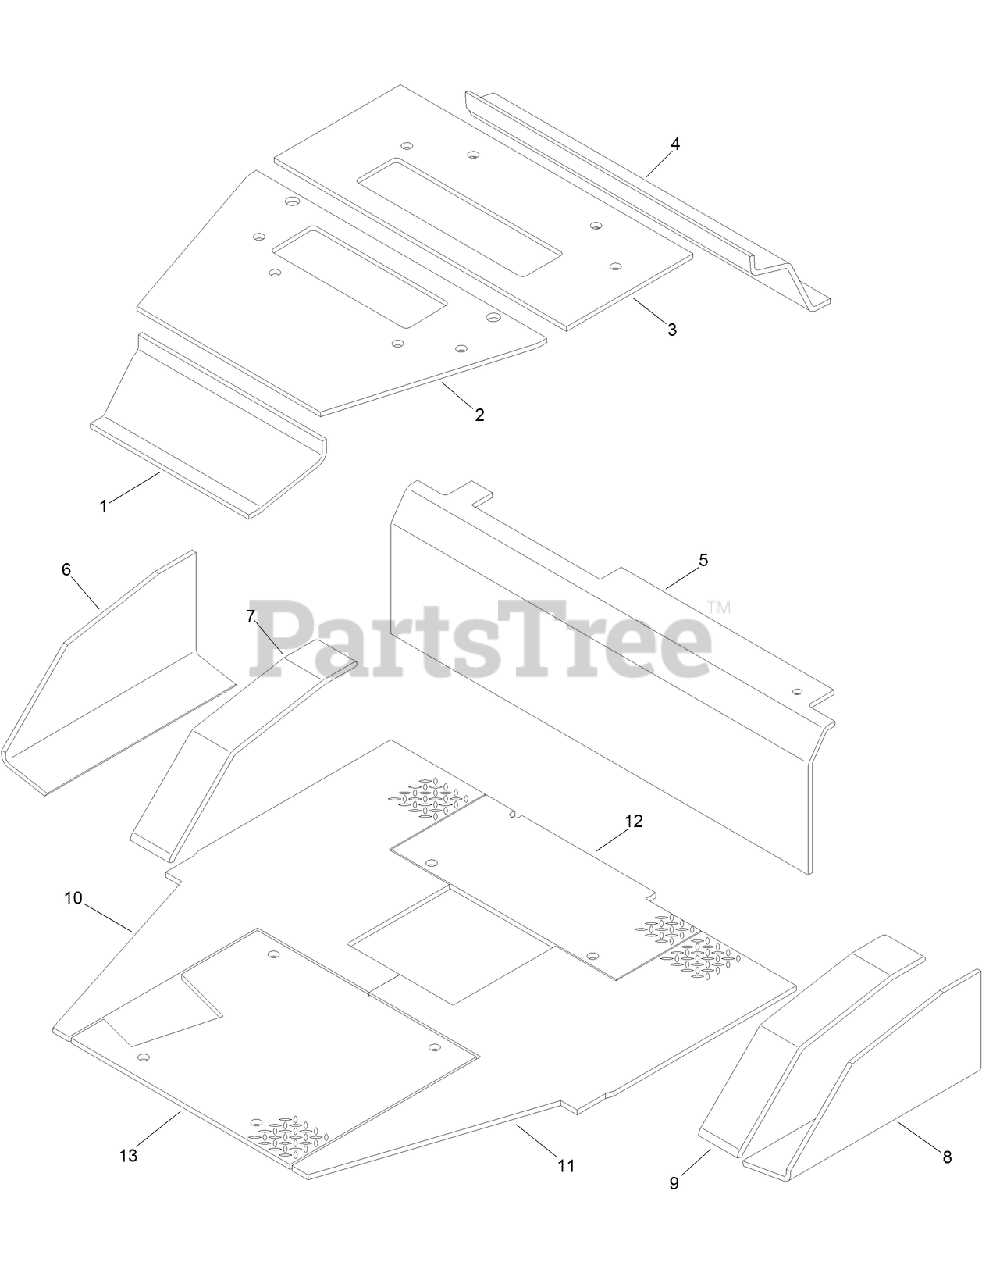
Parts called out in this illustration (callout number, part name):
1	POLYFOAM-ROOF, FRONT
2	POLYFOAM-ROOF, CENTER FRONT
3	POLYFOAM-ROOF, CENTER REAR
4	POLYFOAM-ROOF, REAR
5	POLYFOAM-PANEL, REAR
6	POLYFOAM-CONSOLE, RH BOTTOM
7	POLYFOAM-CONSOLE, RH TOP
8	POLYFOAM-CONSOLE, LH BOTTOM
9	POLYFOAM-CONSOLE , LH TOP
10	FLOORMAT-RH
11	FLOORMAT-LH
12	FLOORMAT-REAR
13	FLOORMAT-FRONT
